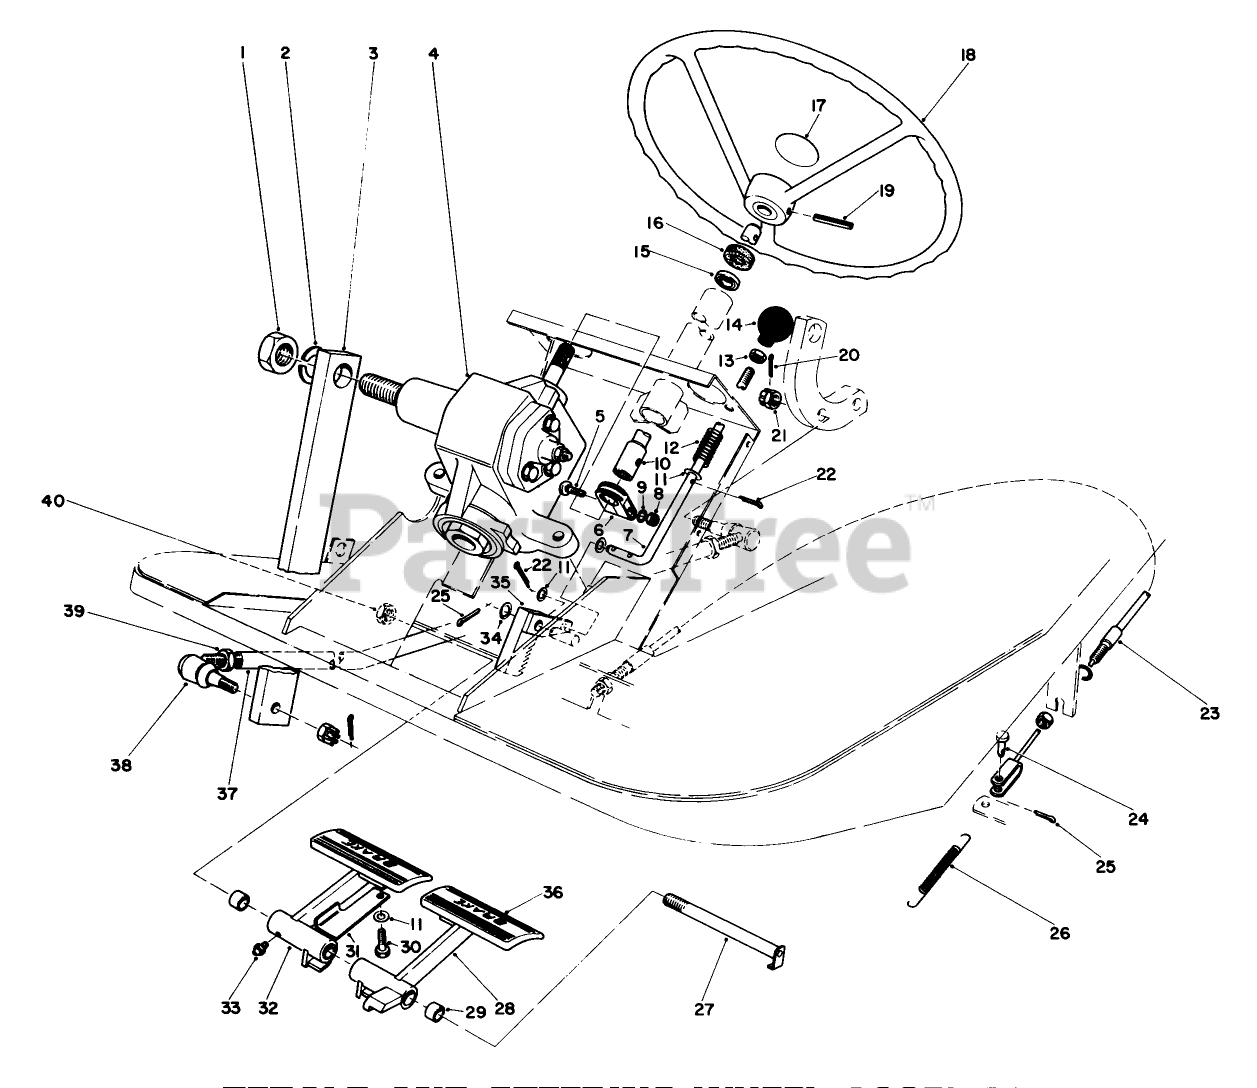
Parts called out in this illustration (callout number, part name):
1	NUT-JAM
2	WASHER-LOCK/SP
3	Pitman Arm
4	Steering Gear
5	7/16-14 X 1-3/4 BOLT
6	STRG COUPLING CLAMP
7	Rod Brake Latch
8	NUT-HEX
9	WASHER-LOCK
10	Shaft-Steering
11	WASHER-FLAT
12	Spring
13	NUT-HEX
15	BALL BRG
16	COVER-DUST
17	STEERING WHEEL CAP
18	STEERING WHEEL
19	PIN-ROLL
20	PIN-COTTER
21	Jam Nut
22	PIN-COTTER
23	RH BRAKE CABLE ASM
24	PIN-CLEVIS
25	PIN-COTTER
26	SPRING-EXTENSION
27	Pin
28	Brake Pedal L.H. (Incl.Ref.#29 & 33)
29	BUSHING
30	Capscrew
31	Latch Parking Brake
32	Brake Pedal R.H. (Incl.Ref.#29 & 33)
33	FITTING-GREASE
34	WASHER-FLAT
35	Rack
36	PAD-BRAKE
37	FRONT STEERING TUBE B
38	Socket Assembly R.H. (Incl.Ref.#21)
39	NUT-JAM
40	NUT-LOCK, NI
